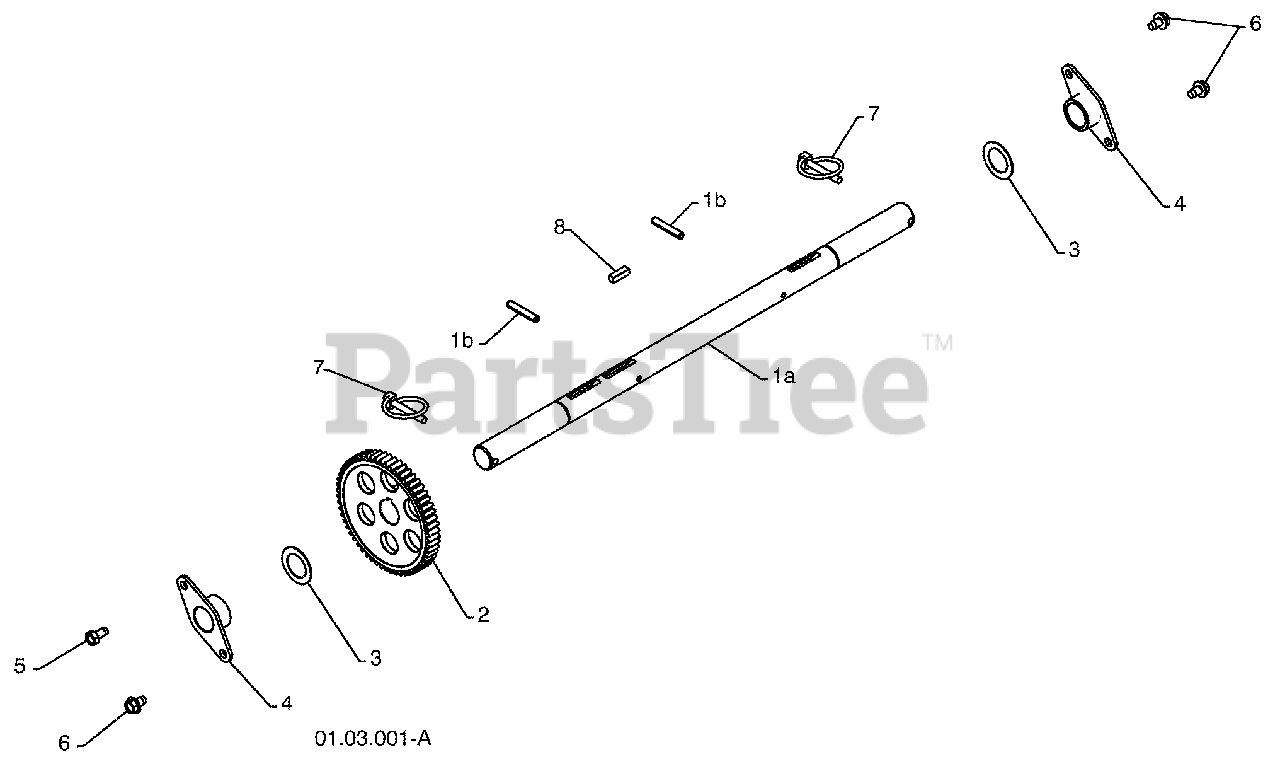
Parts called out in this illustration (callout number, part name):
1	(assy of 1a,1b) AXLE ASSEMBLY
2	GEAR
3	THRUST WASHER
4	AXLE BEARING
5	SCREW 5/16-18 X .625
6	BOLT 5/16-18 X .500
8	SQUARE KEY
